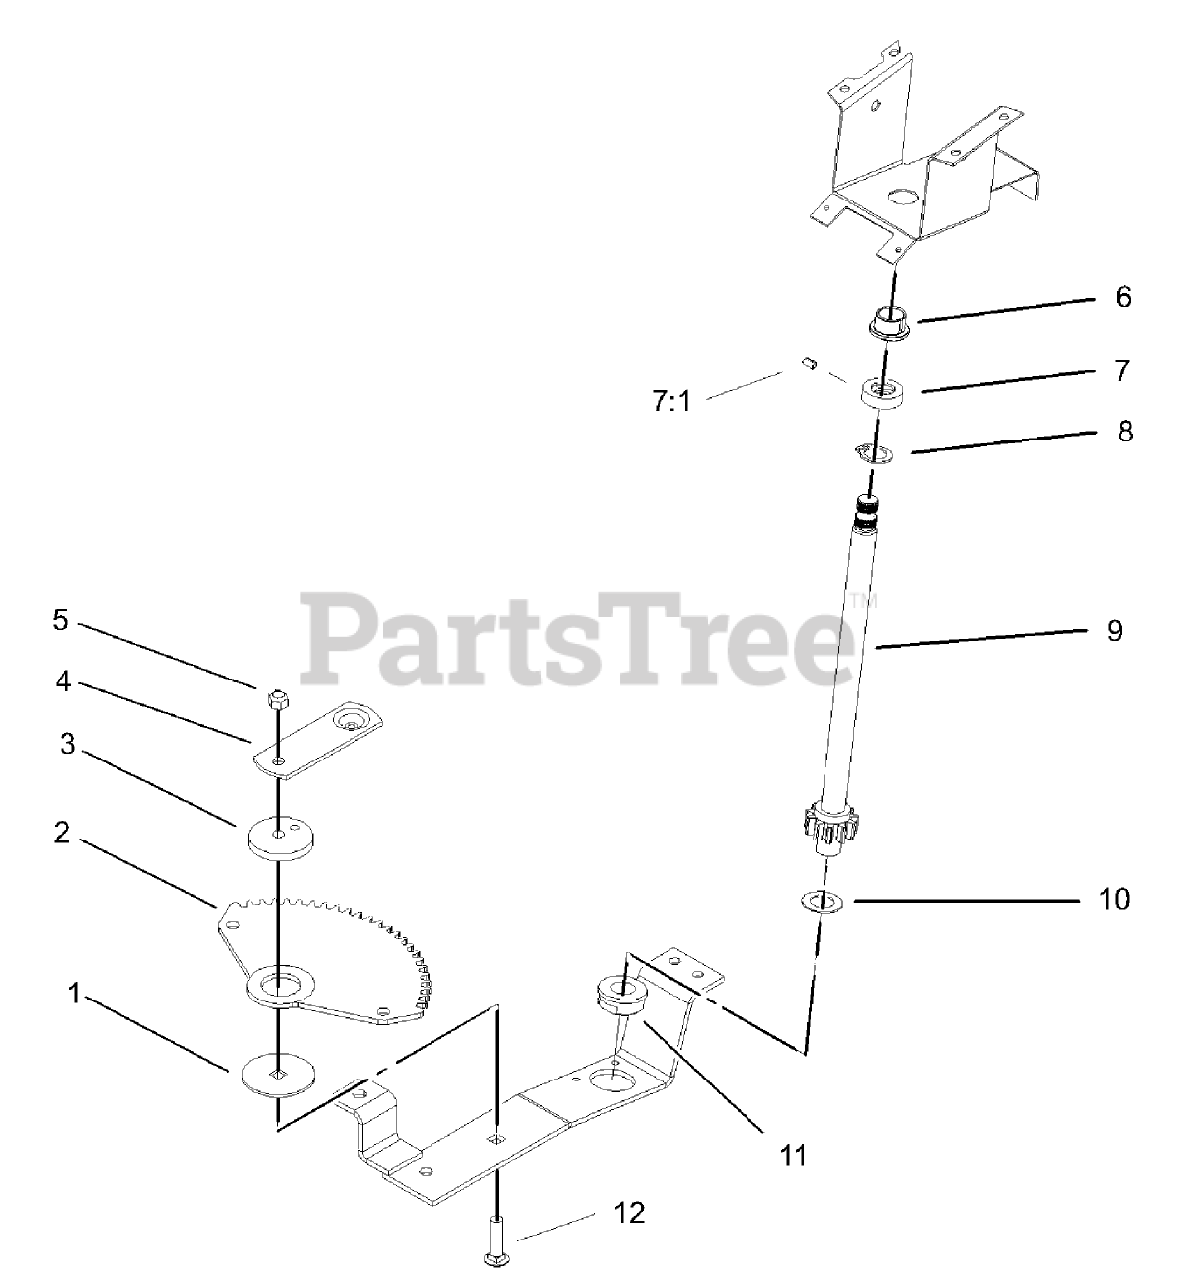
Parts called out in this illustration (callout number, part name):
1	WASHER-BEARING
2	SECTOR-GEAR
3	BUSHING
5	NUT-HEX
6	BEARING-FLANGED
7	COLLAR
7:1	SCREW-HSH
8	RING-RETAINING
9	SHAFT-STEERING, LOWER
10	WASHER
11	BEARING-WHEEL
12	SCREW-CARR
